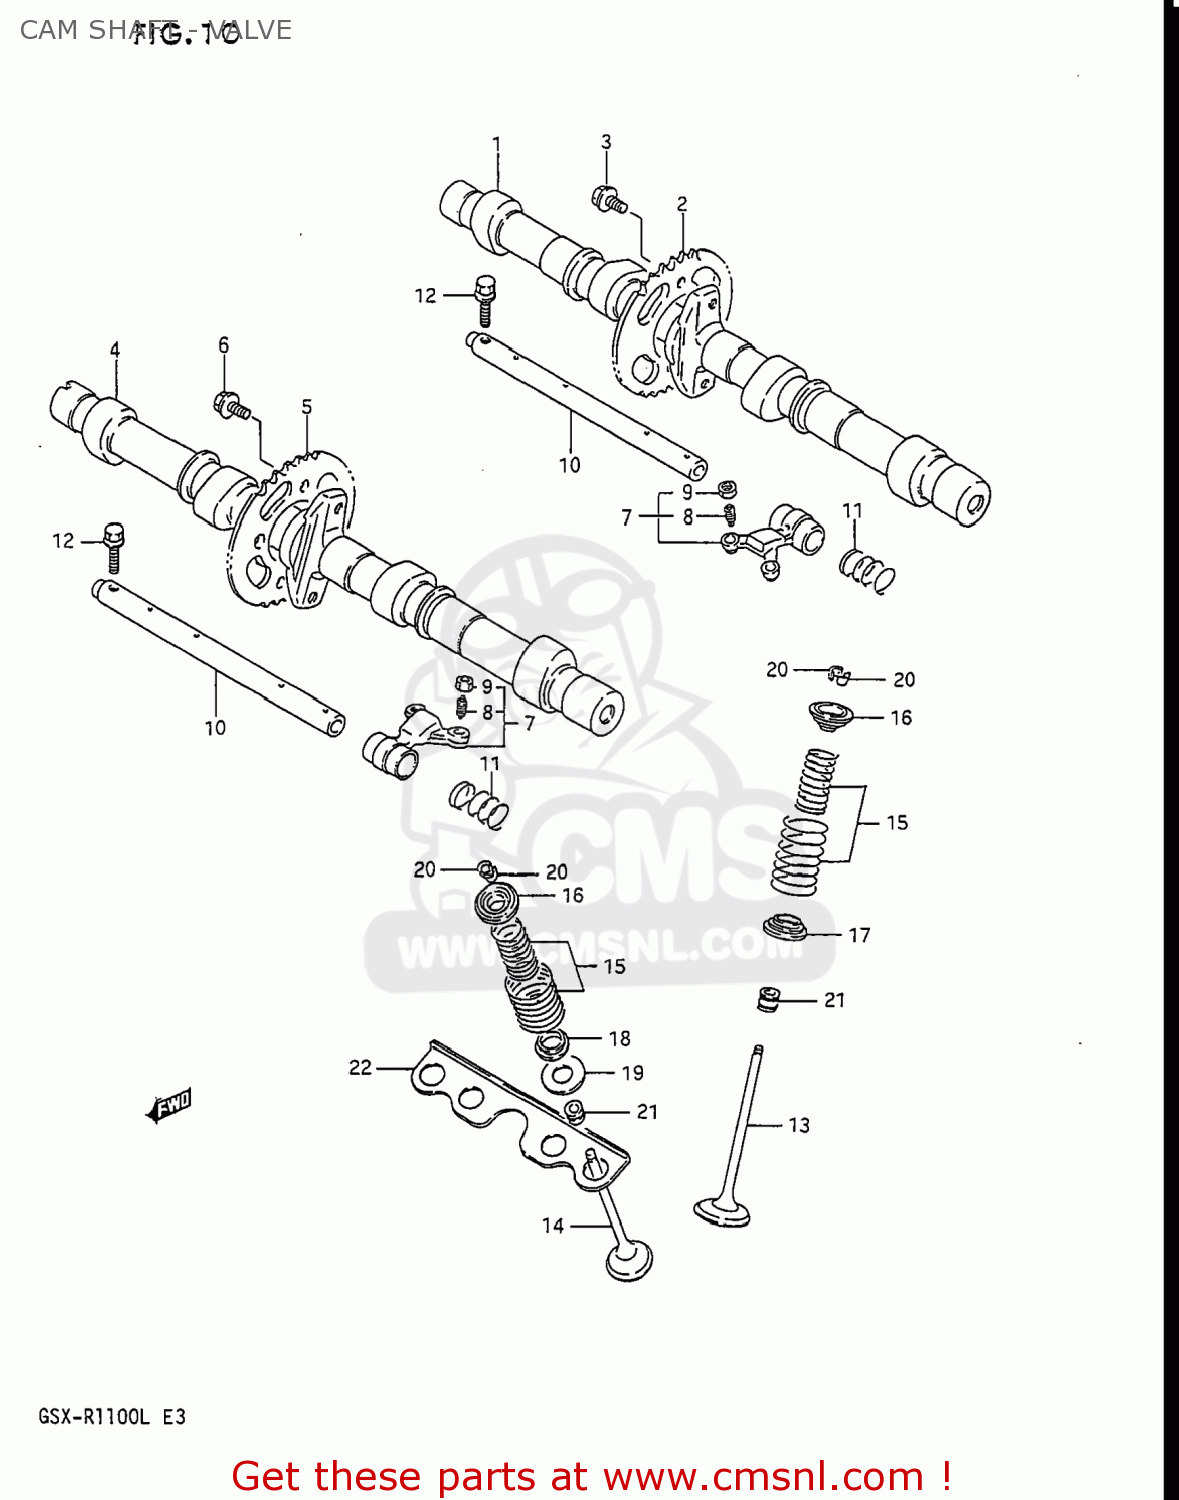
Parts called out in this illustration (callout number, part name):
1	CAMSHAFT
2	SPROCKET,CAMSHAFT
3	BOLT(7X11)
4	CAMSHAFT,EXHAUST
5	SPROCKET,CAMSHAFT
6	BOLT(7X11)
7	ARM,VALVE ROCKER
8	SCREW,TAPPET ADJUSTING
9	NUT,ADJUSTING
10	SHAFT,VALVE ROCKER ARM
11	SPRING
12	BOLT
13	VALVE,INTAKE
14	VALVE,EXHAUST
15	SPRING SET,VALVE
16	RETAINER,VALVE SPRING
17	SEAT,VALVE SPRING
18	SEAT,VALVE SPRING
19	SEAT,VALVE SPRING EXH OUTER
20	COTTER VALVE
21	SEAL,OIL(5X10X9.7)
22	PLATE
